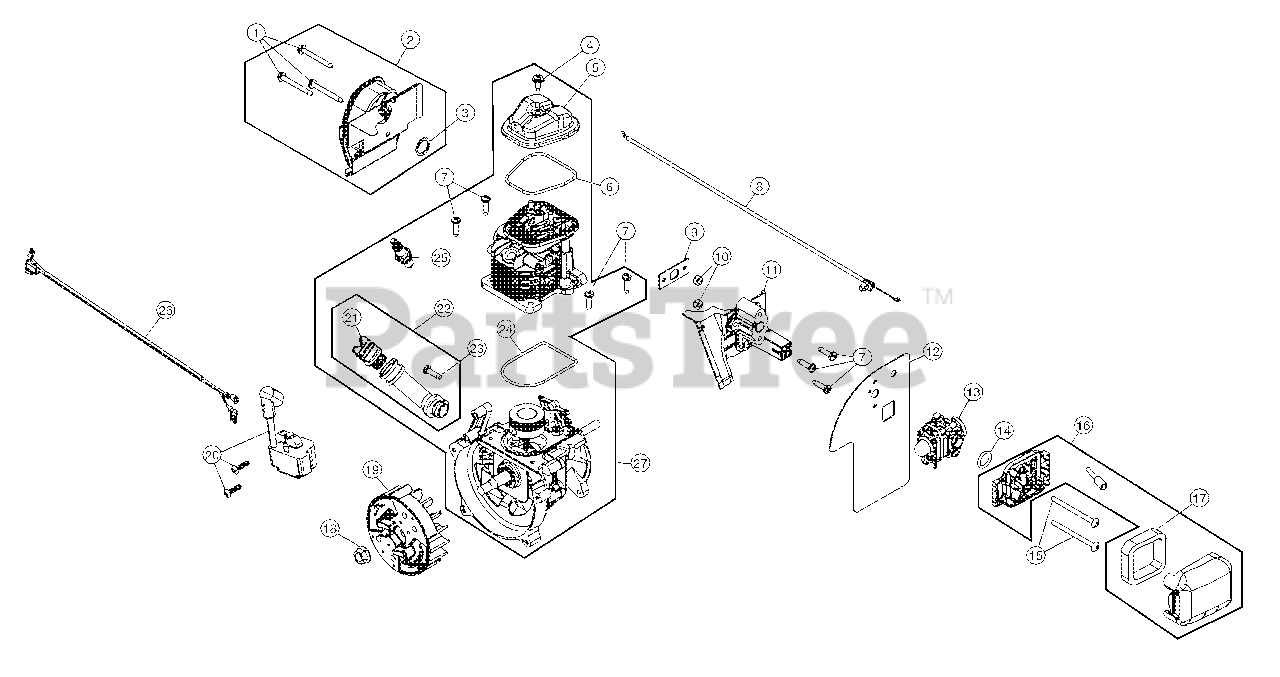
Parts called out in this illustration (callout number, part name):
1	Muffler Screws
2	Muffler Assembly (Incl. 1 & 3)
3	Muffler Gasket
5	Rocker Cover
6	O-Ring
7	Screw
8	Throttle Cable
9	Insulator Gasket
11	Insulator
12	Carburetor Gasket
13	Carburetor
14	Carburetor O-Ring
16	Air Cleaner Assembly (Incl. 17)
17	Air Filter
19	Flywheel Assembly
20	Module
21	Oil Plug
22	Oil Fill Tube (Incl. 23)
24	O-Ring
25	Spark Plug
26	Lead Wire
27	Shortblock Assembly (Incl. 4-7 & 21-25)
